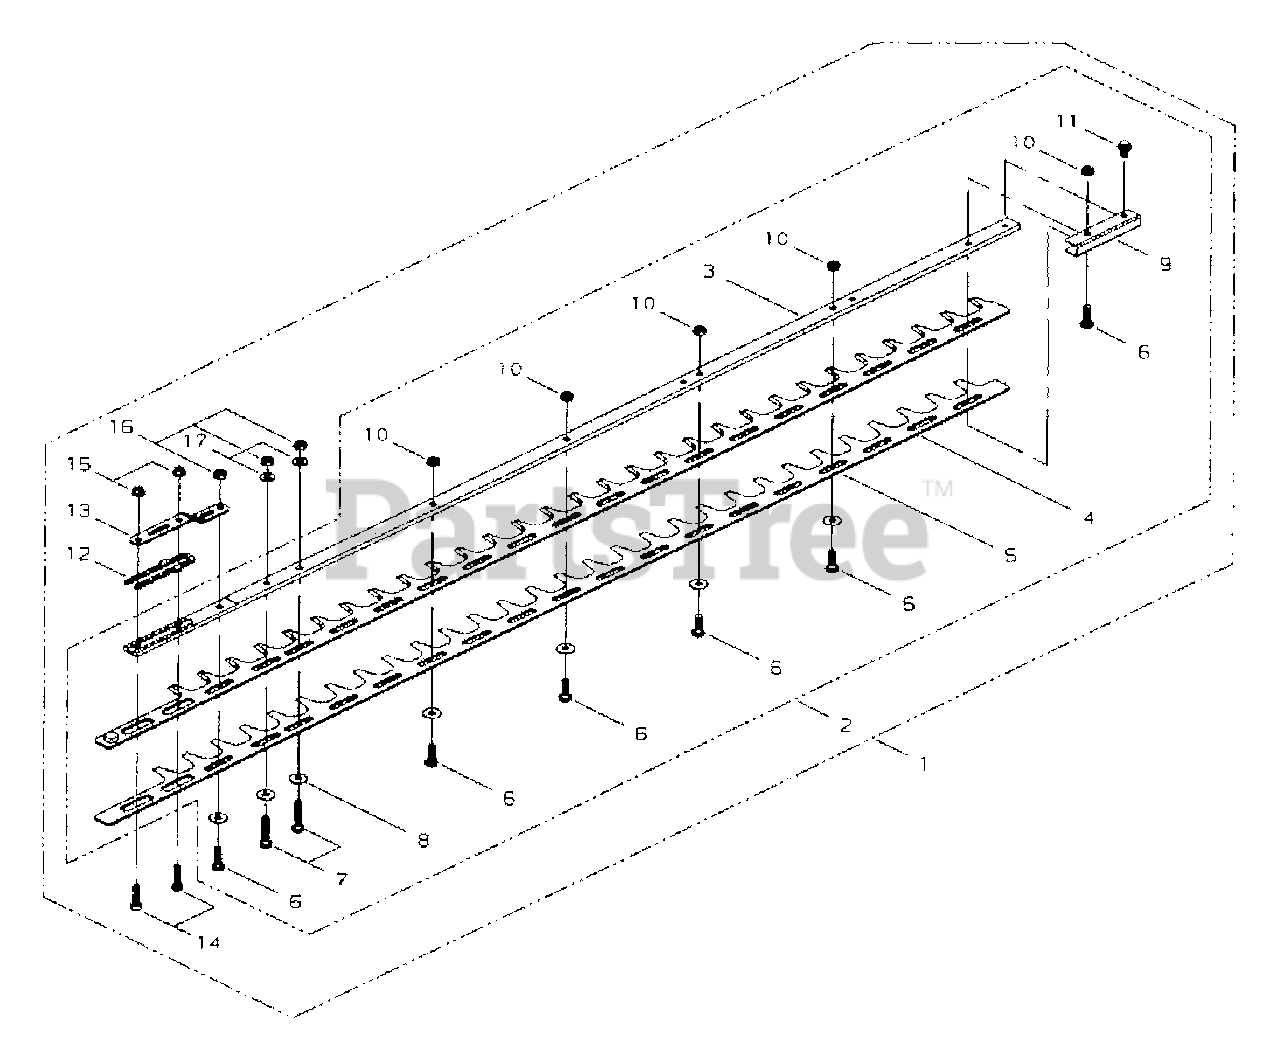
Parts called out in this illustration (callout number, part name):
1	BLADE KIT - 40" (102cm)
2	BLADE KIT - 40" (102cm)
3	SUPPORT, BLADE - 40" (101cm)
4	BLADE - 40" (101cm) HD - UPPER
5	BLADE - 40" (101cm) HD - LOWER
6	BOLT - 6X20
7	BOLT - 6X32
8	WASHER - 6
9	PLATE, GUIDE
10	NUT - 6
11	BOLT - 5X8
14	SCREW - 5X25
15	NUT - 5
16	NUT - 6
17	WASHER - 6
